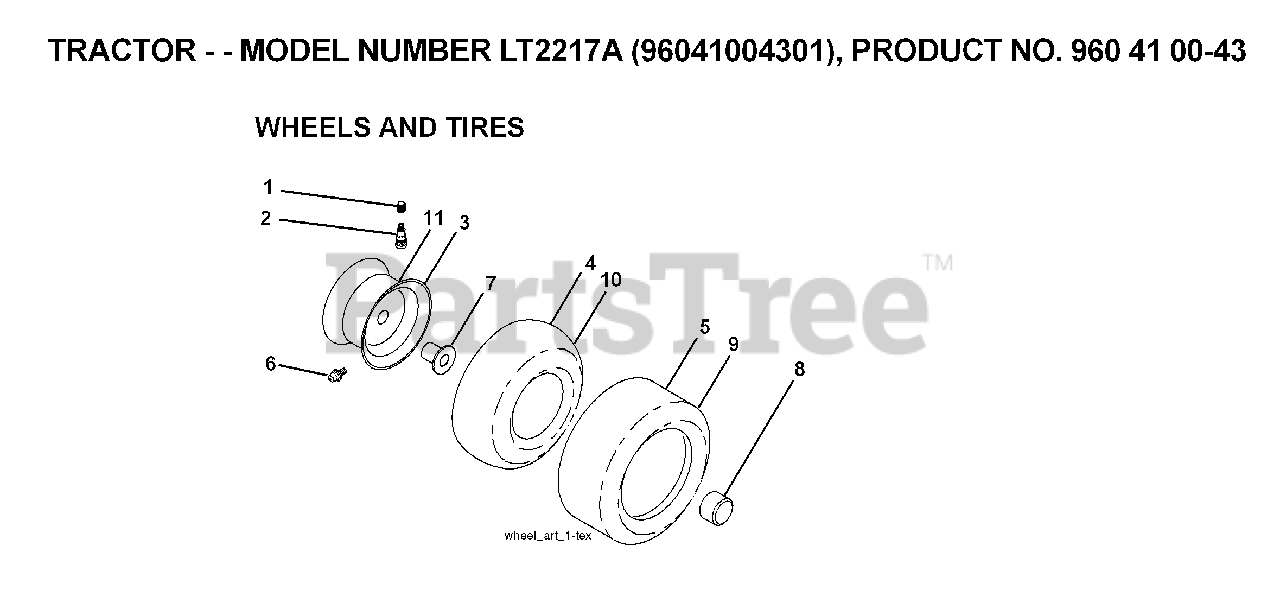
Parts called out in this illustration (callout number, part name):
1	VALVE CAP
2	VALVE STEM LT
3	RIM ASM 6" FRONT SILVER
4	TUBE.5.3/4.5/6
5	TIRE HEAVY DUTY
6	FITTING LT
7	BEARING T
8	CAP, AXLE BLK
9	TIRE HEAVY DUTY
10	TUBE
11	RIM ASM 8" REAR SILVER
